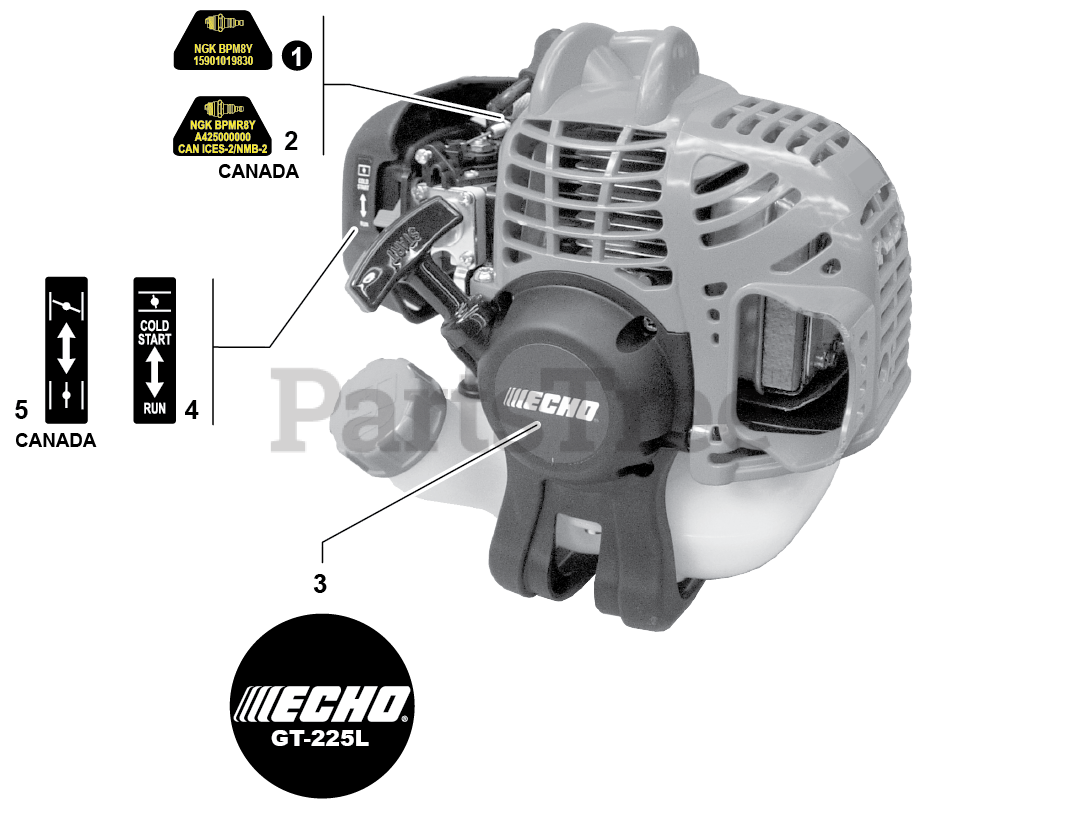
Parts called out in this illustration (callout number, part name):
1	LABEL - SPARK PLUG - BPM8Y
2	LABEL - SPARK PLUG - BPMR8Y
3	LABEL - MODEL - GT-225L
4	LABEL - CHOKE
5	LABEL - CHOKE
